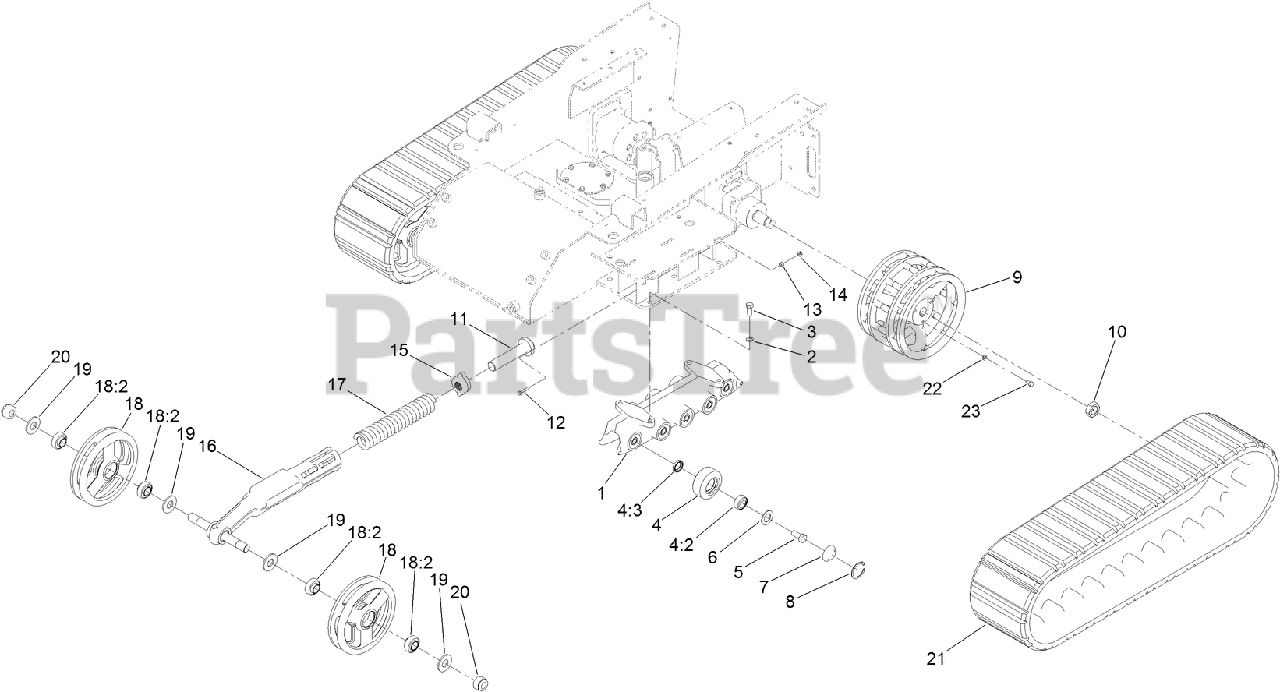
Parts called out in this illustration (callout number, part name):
1	GUIDE-TRACK
2	SCREW-HH
3	SCREW-HH
4	ROAD WHEEL ASM
4:2	BEARING-BALL
4:3	SEAL-OIL
5	SCREW-HH
6	GASKET-BOGIE
7	CAP-WHEEL, BEARING
8	RING-SNAP, INTERNAL
9	WHEEL-DRIVE
10	NUT-HEX
11	BOLT-TENSIONER
12	SCREW-HH
13	SPACER
14	NUT-HHF
15	BLOCK-TENSIONER
16	ARM-TENSIONER
17	SPRING-COMPRESSION
18	TENSIONER WHEEL ASM
18:2	BEARING-BALL
19	WASHER-PLAIN
20	NUT-HEX, NI
22	WASHER-LOCK
23	SCREW-HH
